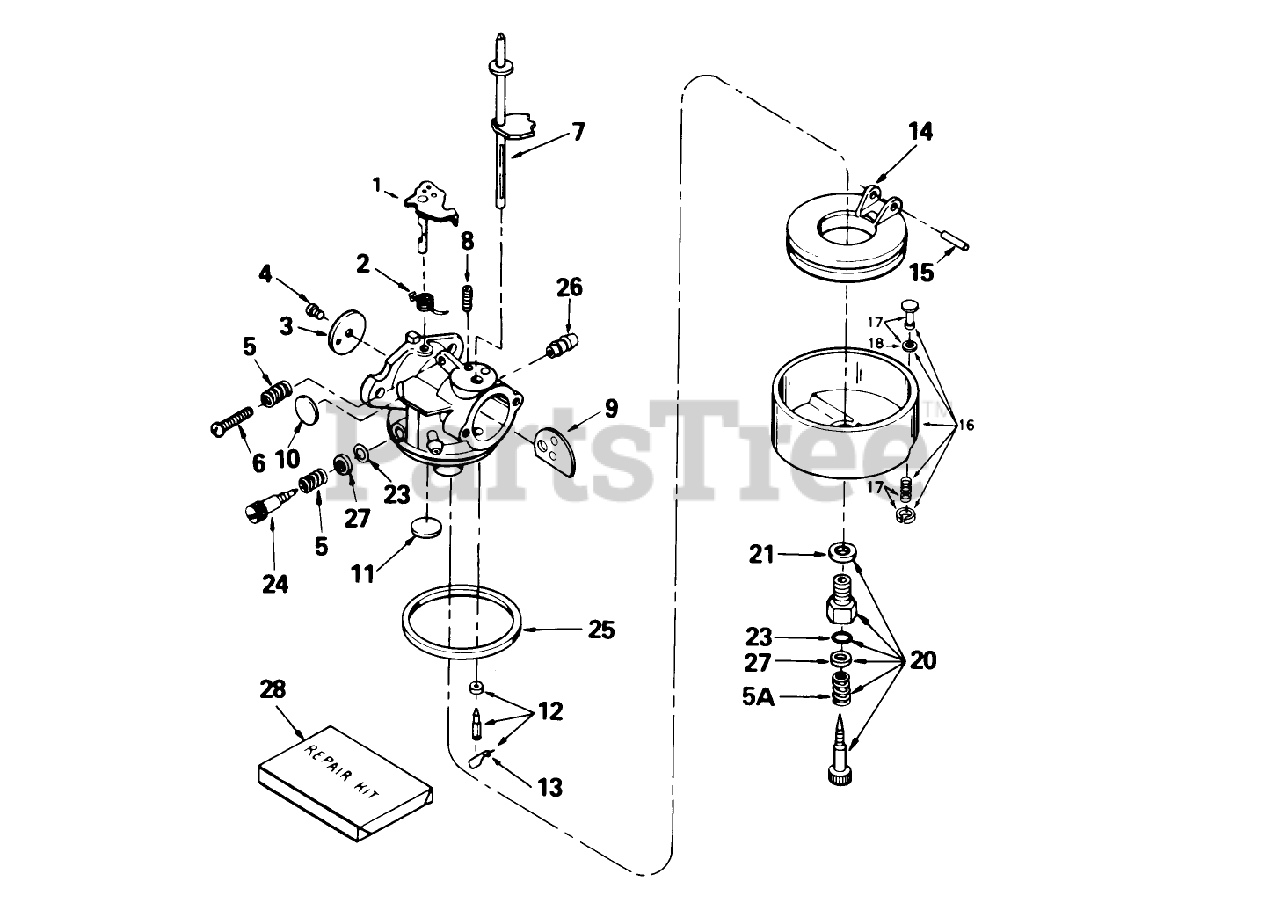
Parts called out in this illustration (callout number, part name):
1	Shaft/Lever-Throttle
2	Spring-Return, Throttle
3	Shutter-Throttle
4	Screw-Shutter
5	Spring-Tension
5A	Spring
6	Screw-Throttle Crack Screw / Idle Speed
7	Shaft-Choke
8	Spring-Positioning, Choke
9	Shutter-Choke
10	Plug-Welch, Idle Mixture Well
11	Plug-Welch, Atmospheric Vent
12	Inlet Needle, Seat Clip Assy. (Incl. No. 13)
13	Clip-Spring
14	Float
15	Shaft-Float
16	Float Bowl Asm. (Incl. Ref. # 32, 33)
17	Bowl Drain ASM
18	Gasket-Plunger, Drain
20	Adjustment Screw Assy., Main (Incl. Nos. 5A, 21 23)
21	Washer-Bowl Nut
23	ORing
24	Screw-Idle
25	O Ring-Bowl, Float
26	Fitting-Fuel
27	Washer
28	Repair Kit (Incl. items marked *)
